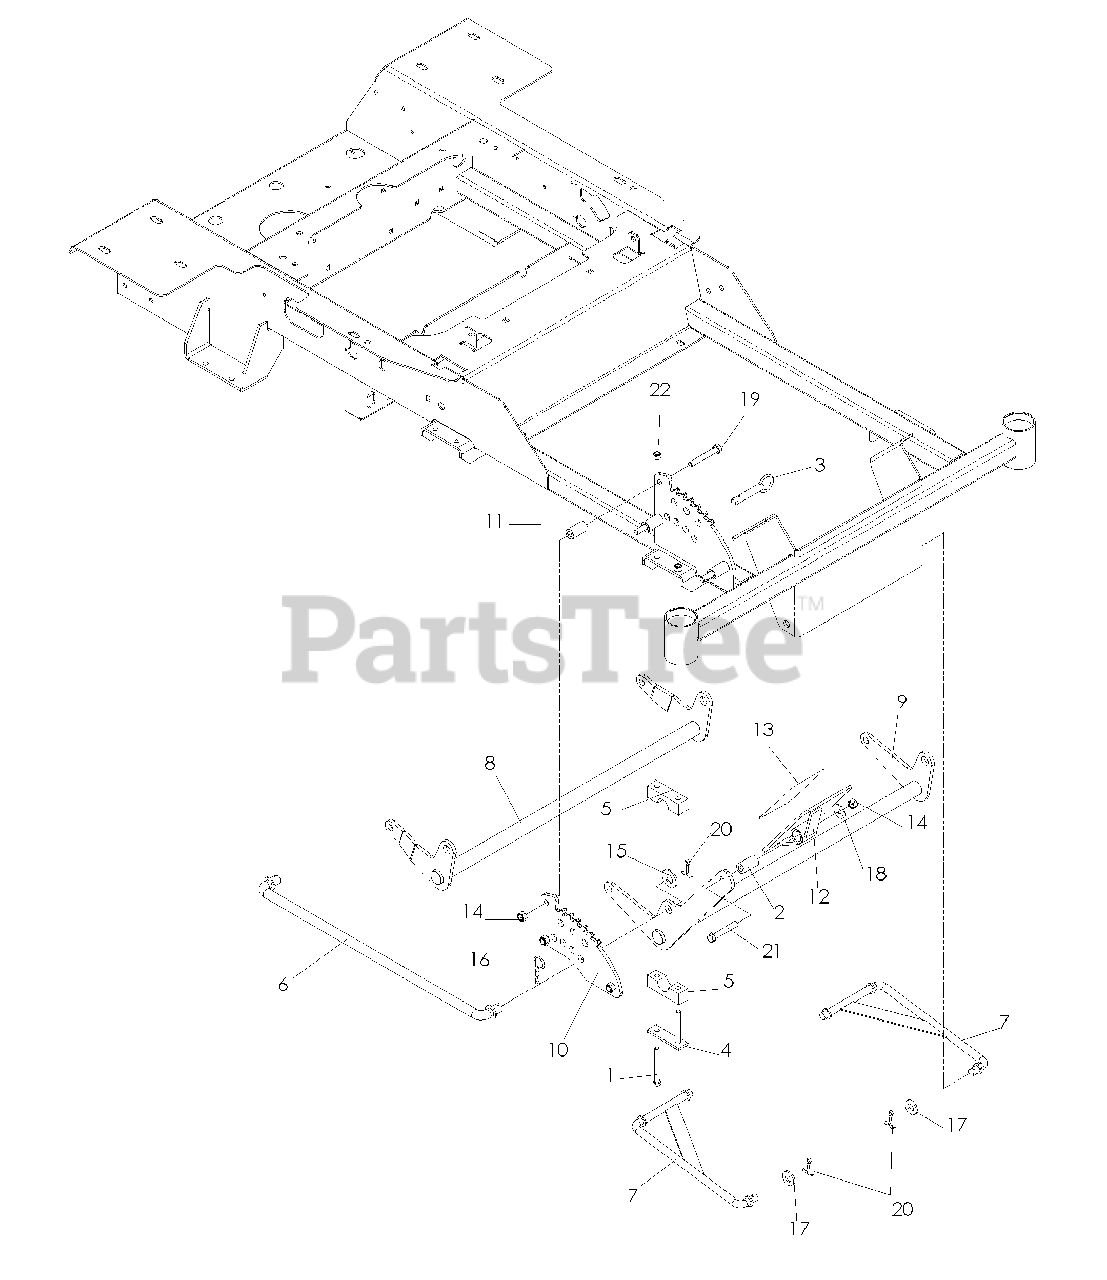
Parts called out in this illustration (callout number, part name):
1	HCS 5/16C X 2-3/4
2	BUSHING, SLEEVE
3	HITCH PIN
4	REINFORCEMENT BAR
5	PILLOW BLOCK
6	CROSS LINK
7	STRUT LINKAGE
8	LIFT SHAFT, REAR
9	LIFT SHAFT, FRONT
10	PLATE, HEIGHT, OUTER
12	PEDAL, FOOT, WELDMENT
13	FOOT PAD
14	NUT 3/8-16 NYLOC
15	WASHER 5/8 FLAT
16	HAIRPIN #4
17	WASHER 1/2" FLAT
18	WASHER 3/8 FLAT
19	HCS 3/8C X 2 1/2
20	COTTER PIN
21	HCS 3/8C X 2 1/4
22	NUT 5/16 NYLOC
